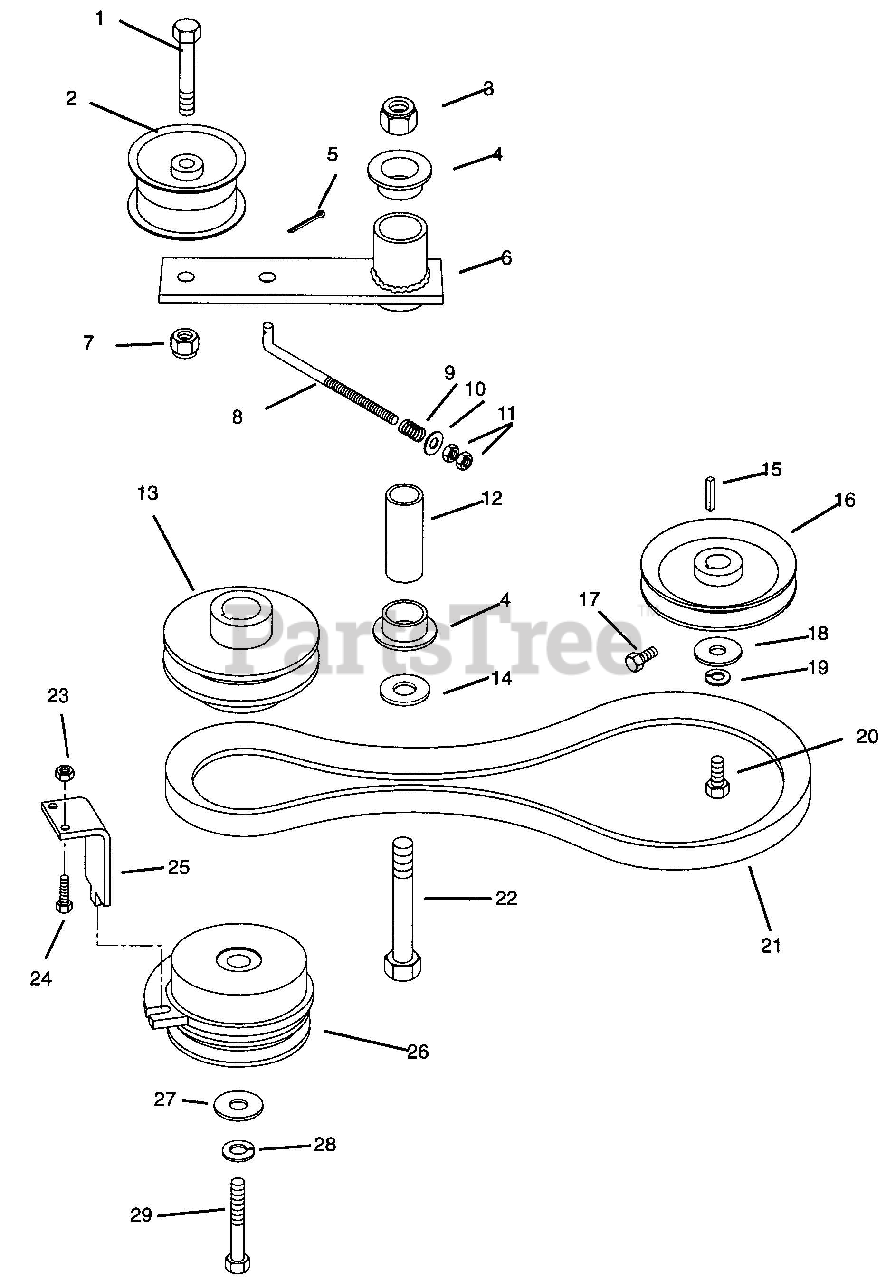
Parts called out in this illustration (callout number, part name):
1	Bolt-Hex .38-16 x 1.75 Grade 5
2	Idler-Pulley-Flat 3.25 x .625
3	Nut-Locking-Center .50-13 Grade 5
4	Bushing-Flange .762 x 1.0 x .580 x 1.48
5	Pin-Cotter .09 x .75
6	Weldment - Ground Drive Idler
7	Nut-Locking-Center .375-16 Grade 2
8	Rod - Idler
9	Spring-Compression .125 x .78 x 1.00
10	Washer-Flat-Steel .406 x .812 x .065
11	Nut-Hex .375-24 Grade 2
12	Bushing-Steel .560 x .745 x 2.04
13	Sheave - Engine
14	Washer-Flat-Steel .531 x 1.062 x .095
15	Key - Straight 5mm x 25mm x 5mm
16	Sheave 4.0 x .199
17	Bolt-Hex .25-20 x .50 Grade 5
18	Washer-Flat-Steel .281 x 1.250 x .062
19	Washer-Lock .250 Reg.
20	Bolt-Hex M6 x 1.0 x 12mm Lg
21	V-Belt-A-RMA 24.50 x 33/64
22	Bolt-Hex .50-13 x 3.00
23	Nut-Locking-Center .312-18 Grade 2
24	Bolt-Hex .31-18 x 1.00 Grade 5
25	Clutch Stop
26	Clutch - Electric
27	Washer-Special .469 x 2.000 x .250
28	Washer-Lock .44 Reg.
29	Bolt-Hex .44-20 x 3.00
